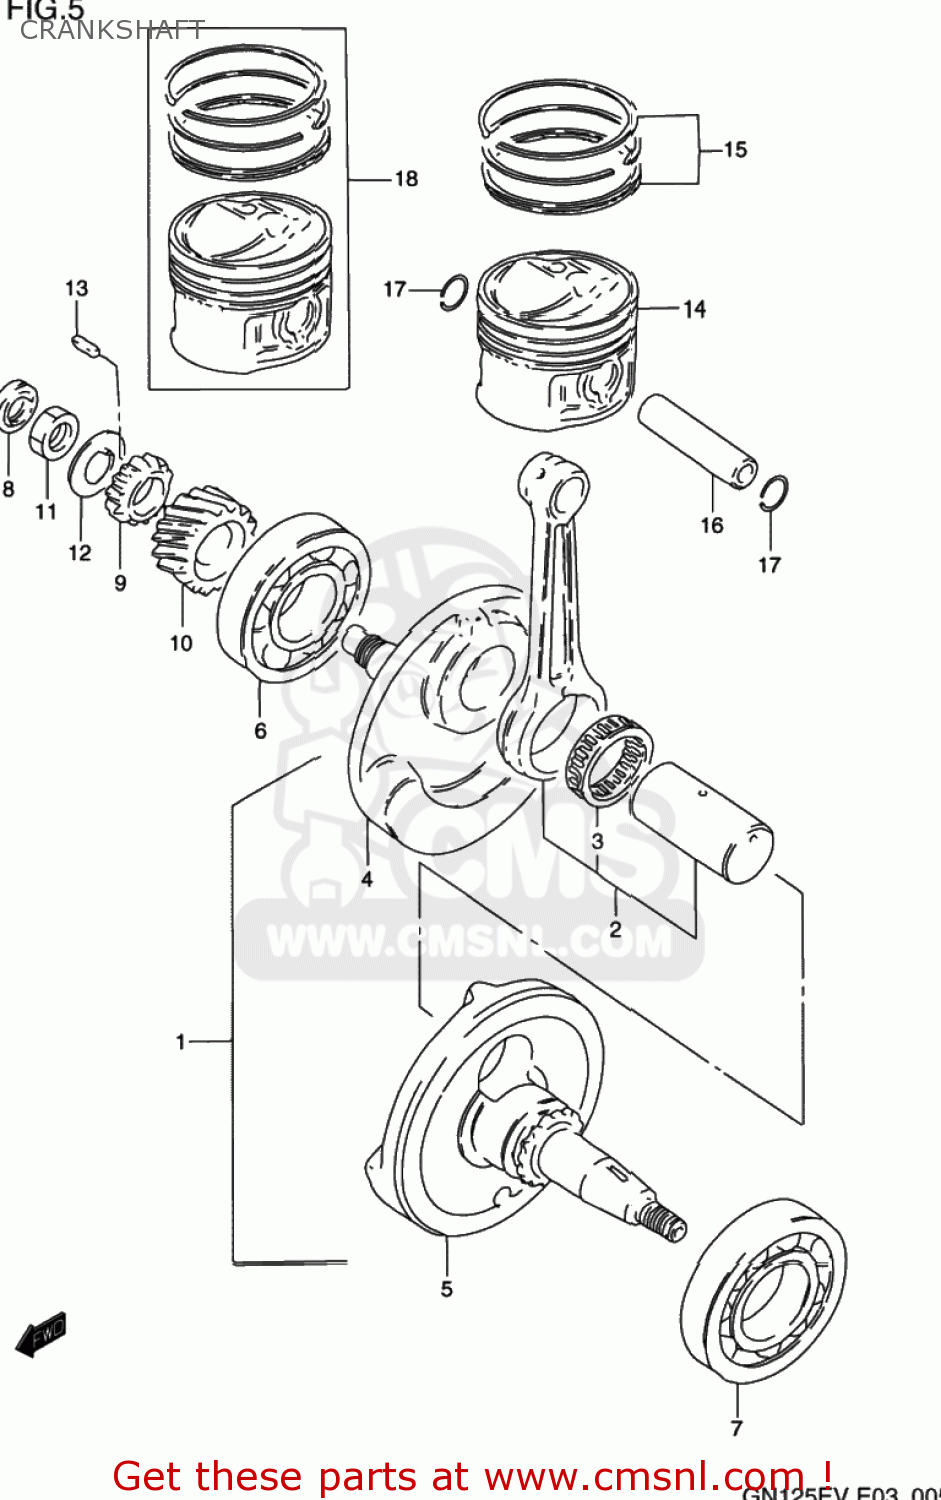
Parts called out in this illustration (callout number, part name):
1	CRANKSHAFT ASSEMBLY
2	CONNECTING ROD SET
3	BEARING(28X36X15.8)
4	CRANKSHAFT,RIGHT
5	CRANKSHAFT,L
6	BEARING(28X68X18)
7	BEARING(35X72X17)
8	SEAL,OIL(12X21X7)
9	GEAR,OIL PUMP DRIVE
10	GEAR,PRIMARY DRIVE
11	NUT
12	WASHER
13	KEY
14	PISTON (STD)
15	RING SET,PISTON
16	PIN,PISTON
17	RING,SNAP 14MM
18	PISTON SET(OS:0.5)
